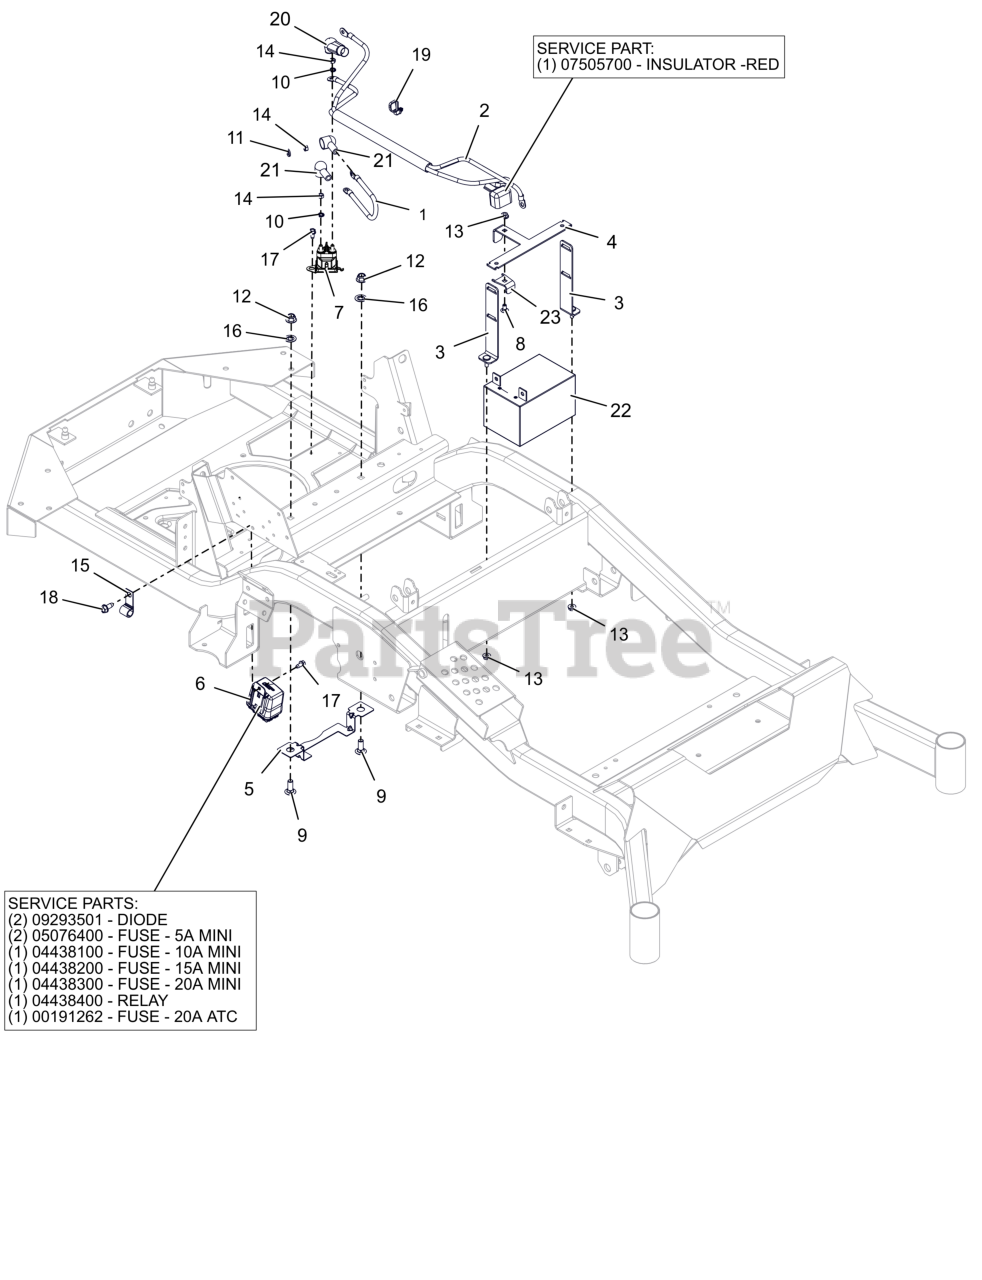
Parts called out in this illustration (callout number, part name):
1	CABLE, POS W/(2)1/4 RING 9.0LG
2	HARNESS, BATTERY HD
2	INSULATOR
3	WMT-BATT MNT HOLD DOWN FORMED
4	BRKT- BATTERY HOLD DOWN
5	GUARD, ELECTRICAL HARNESS
6	HARNESS, WIRE
6	DIODE, CONNECTOR SHELL
6	FUSE, 5 AMP MINI-ATC
6	FUSE,10 AMP MINI-ATC
6	Fuse, 15 AMP MINI-ATC
6	FUSE,20 AMP MINI ATC
6	RELAY,MICRO5 TERML W/RESISTOR
6	FUSE, 20 AMP BLADE S/O
7	SOLENOID, STARTER (SEALED)
8	BLT, RHSN .25-20X.500 G5 ZCC
9	BLT, RHSN .38-16X1.00 G5 ZCC
10	WSHR,LK-EXT.262X.502X.026 ZCC
11	WSHR,LK-REG .312X.078 ZCC
12	NUT,NYL-FLG .38-16 GF ZCC
13	NUT-LK-TOP-FLG .250-20 GF ZCC
14	NUT-STD M6-1.0 ZCC
15	J-CLAMP
16	WSHR, RETAINING .35X.88X.03 NYL
17	SCR-TAP .25-20X.50 HWH ZCC
18	SCR,TAP .312-18X.75 HWH TR ZCC
19	CABLE TIE W/ TREE (.25 HOLE)
20	BOOT, .65ID POS
21	BOOT, EYELET TERMINAL
22	BATTERY, 12V 12AH -190CCA
23	BRKT, BATTERY HOLD
